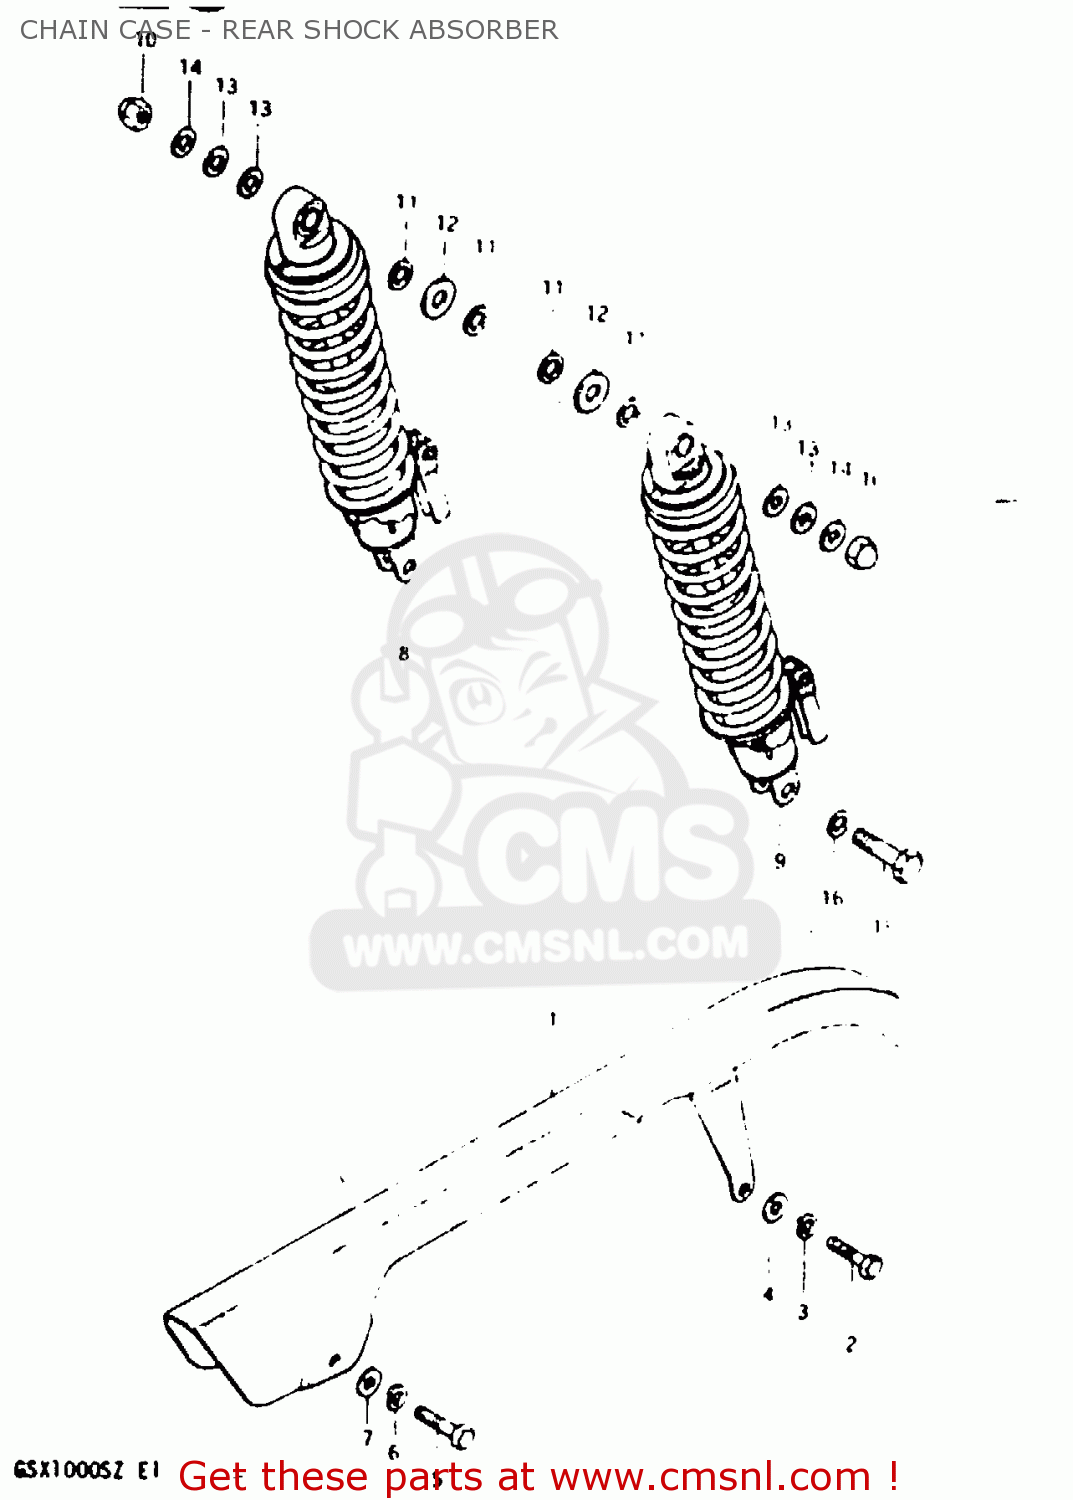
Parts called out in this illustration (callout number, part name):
1	CASE,CHAIN
2	BOLT
3	LOCK WASHER
4	WASHER
5	BOLT
6	LOCK WASHER
7	WASHER
8	SHOCK ABSORBER, REAR RH
9	SHOCK ABSORBER, REAR LH
10	NUT, LOWER LH
11	WASHER
12	WASHER (12.5X24X3.2)
13	WASHER
14	WASHER(10.5X24X3.2)
15	BOLT(10X36)
16	WASHER
